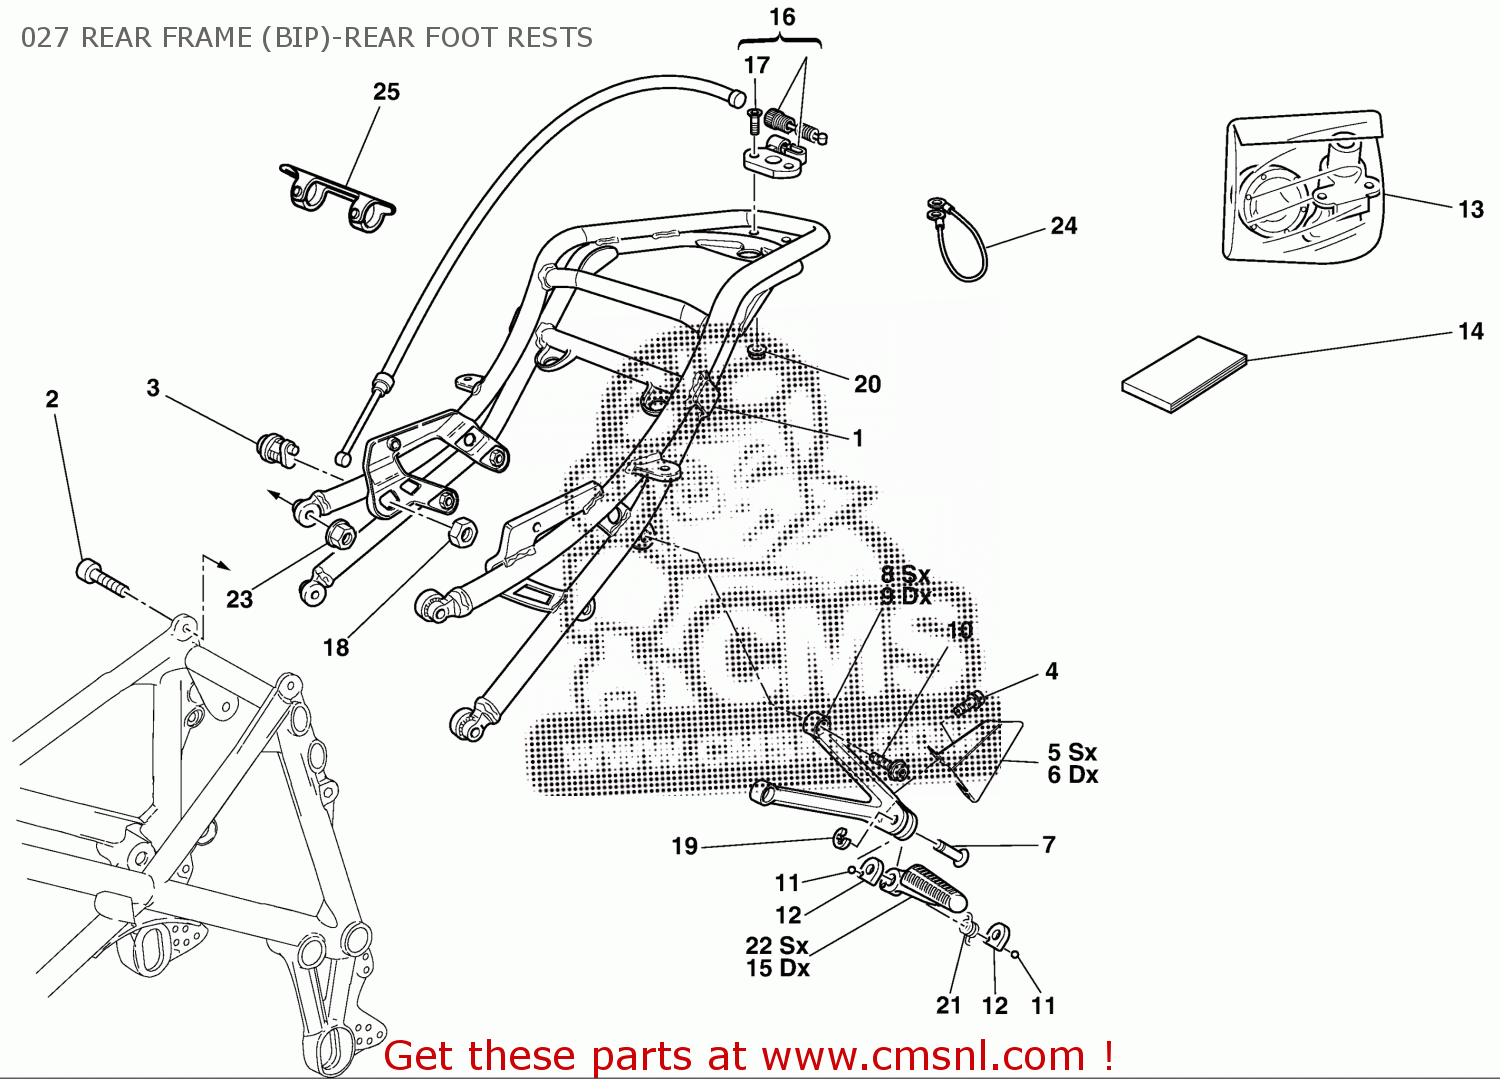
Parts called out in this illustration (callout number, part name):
1	REAR FRAME METALGRAY
2	SCREW
3	SEAT LOCK
4	SCREW TCEIF M5X12
5	GUARD FRONT STEP LH
6	GUARD FRONT STEP RH
7	FOOTREST PIN
8	REAR FOOT REST BRACKET LEFT
9	BRACKET, REAR RIGHT FOOTREST
10	SCREW TCEIF M8X20
11	BALL 1/4
12	PLATE
13	LOCKS KIT
14	OWNERS MANUAL IT-GB-FR-DE
15	REAR RIGHT FOOTREST
16	STRIKER, SEAT LOCK
17	SCREW M5X16
18	NUT
19	CIRCLIP E-TYPE
20	NUT, SELF-LOCKING M5X0.80 CH8
21	SPRING
22	REAR LEFT FOOT-REST
23	NUT M8
24	ANTI-THEFT CABLE
25	CLAMP
